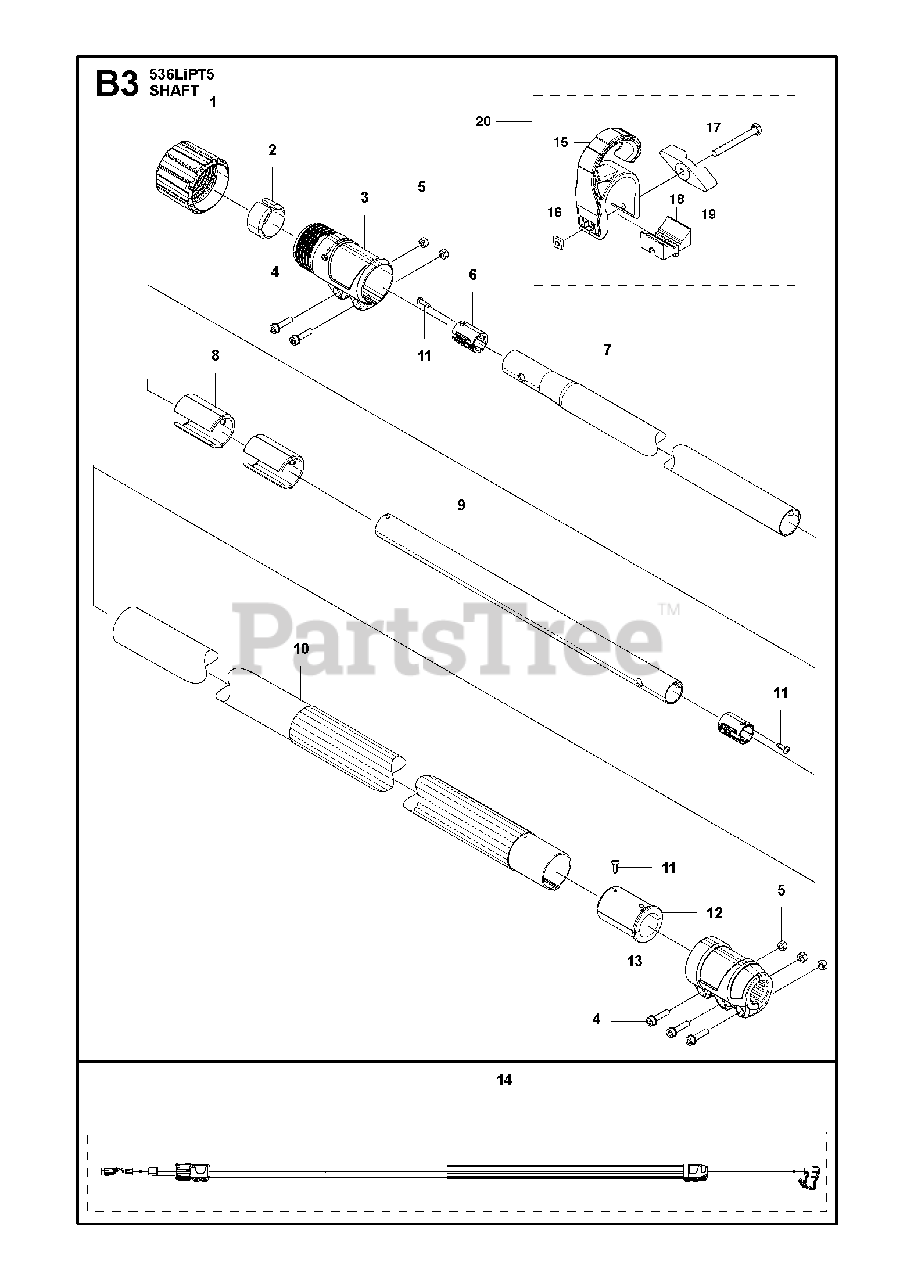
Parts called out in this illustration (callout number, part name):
3	CLAMPING SLEEVE
6	SPACER CABLELOCK
7	Upper Tube
8	Guide Bushing
9	Lower Tube
10	TUBE ASSY LOWER
11	SCREW
13	CLAMPING SLEEVE
14	TUBE ASSY TELESCOPIC
15	LOOP
16	NUT
17	SCREW M6X55
18	LOOP
19	HANDLE
